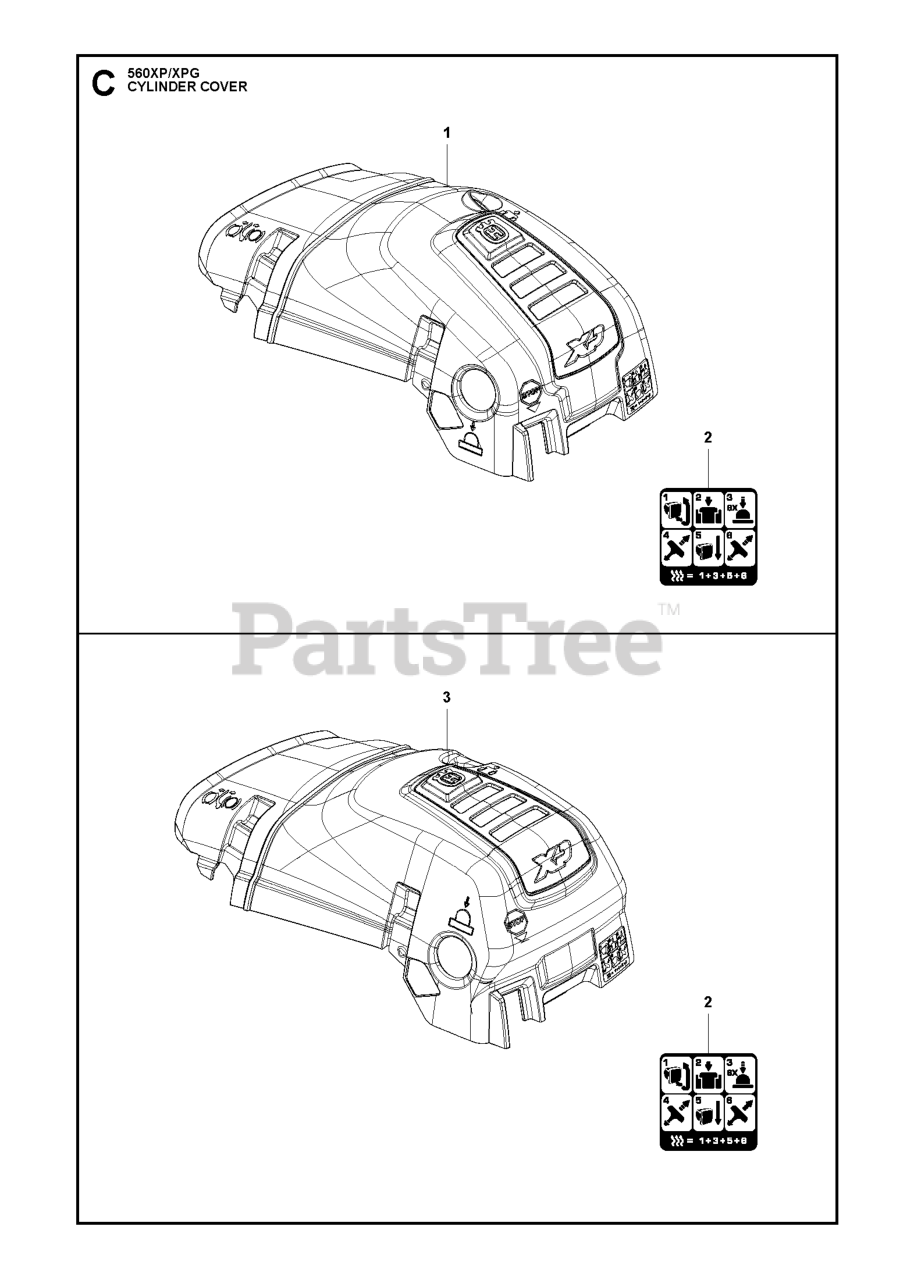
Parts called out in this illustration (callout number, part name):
1	CYLINDER COVER ASSY
2	LABEL STARTER REMINDER
3	COVER
